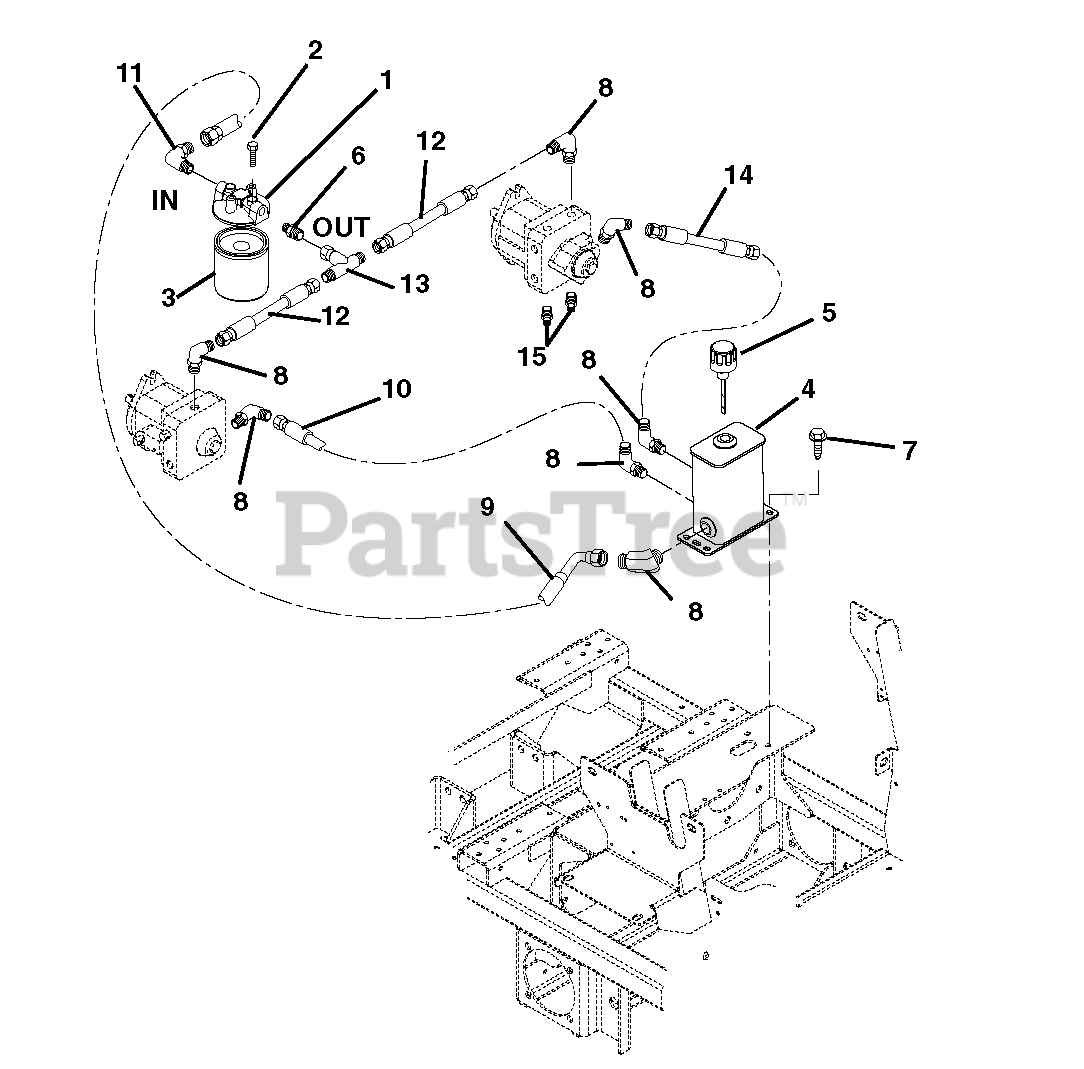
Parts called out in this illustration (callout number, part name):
1	Head, Filter
2	Bolt, Hex .25-20 x .50 Grade 5 Epoxy
3	Oil Filter
4	Weldment,Formed 3-Port
5	Hydraulic Tank Dipstick
6	Fitting, Hydraulic, Straight
7	Screw, Tapping .38-16 x .75 Hex Washer Head
8	Fitting, Hydraulic, 90 Degree Elbow
9	Hose, Hydraulic Valve to Tank
10	Hose, Hydraulic, 10-inch
11	Fitting, Hydraulic, 90 Degree Elbow
12	Hose, Hydraulic .50, 5-Inch
13	Fitting, Hydraulic Tee
14	Hose, Hydraulic
15	Fitting, Hydraulic (4 F5OLO)
